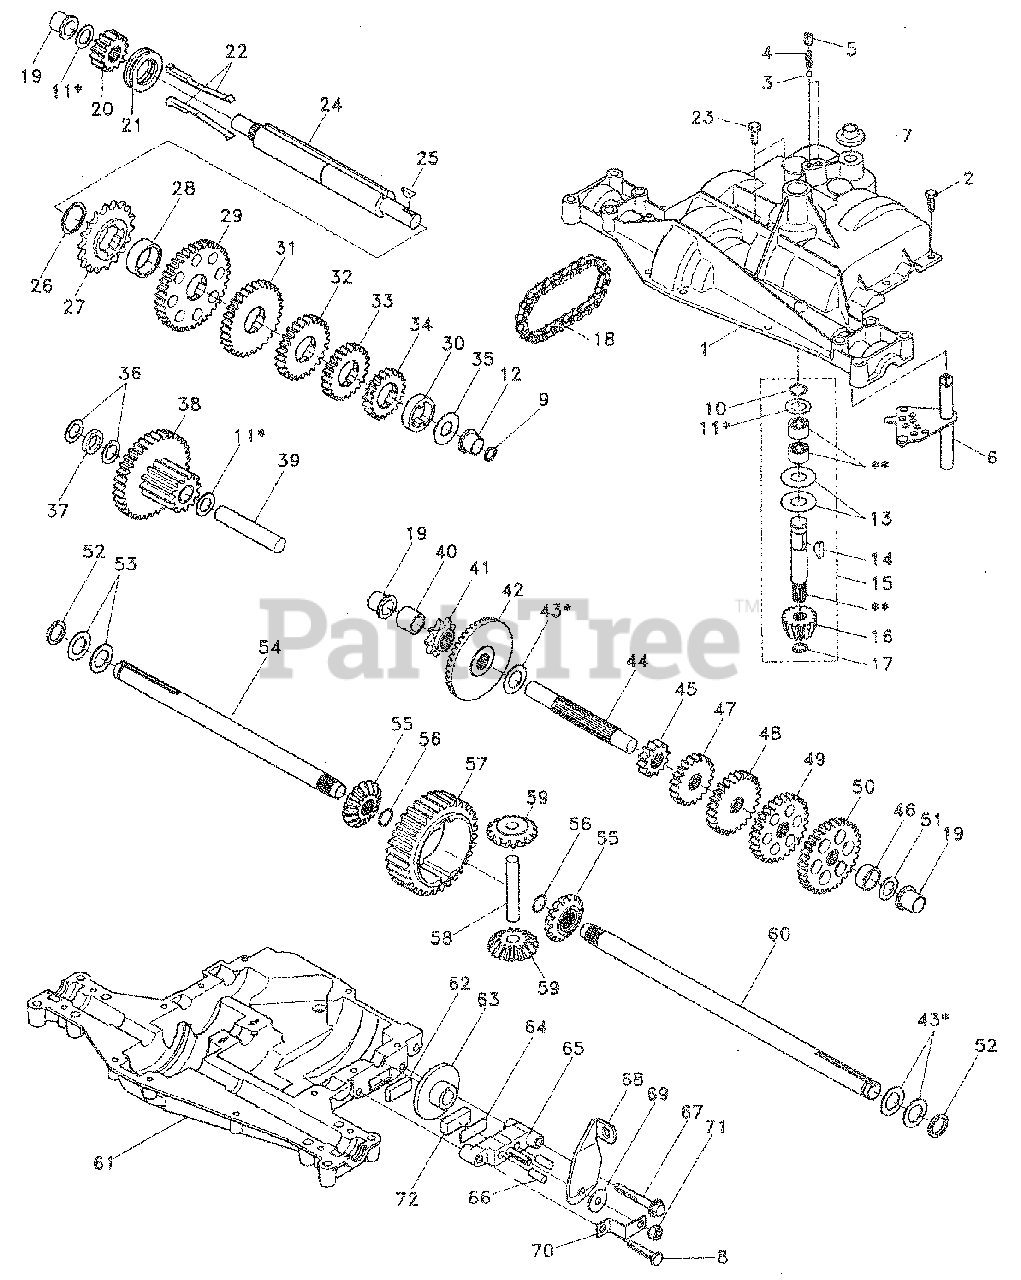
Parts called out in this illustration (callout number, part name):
1	Housing, Upper
2	Screw, Self-Tapping, Large 1/4-20 X.734
3	Ball, Detent
4	Spring, Detent
5	Screw, Set
6	Kit, Shifter Assembly
7	Boot, Shifter
8	Screw, Self-Tapping, Large 5/16-18 x 1.44
9	Square Ring
10	Ring, Retaining
11	Assembly, Kit, Shim .625 Shaft
12	Bearing, Flange
13	Washer, Plain .632 x 1.38 x .046
14	Key, Woodruff, #9
15	Assembly, Kit, Input Shaft
16	Pinion, Bevel, 14 Teeth
17	Ring, Retaining
18	Chain, 24 Pitches
19	Bearing, Flange
20	Gear, Spur, 14 Teeth
21	Collar, Clutch
22	Assembly, Kit, Clutch Keys
23	Screw, Self-Tapping, with Sealer
24	Shaft, intermediate
25	Key, Woodruff, #61
26	Ring, Retaining
27	Sprocket, 18 Teeth
29	Gear, Spur, 37 Teeth
30	Spacer 1.133 x 1.50 x .375
31	Gear, Spur, 30 Teeth
32	Gear, Spur, 25 Teeth
33	Gear, Spur, 22 Teeth
34	Gear, Spur, 19 Teeth
35	Washer, Plain .640 x 1.37 x .061
36	Washer, Plain .632 x 1.00 x .026
37	Spacer .630 x 1.00 x .169
38	Assembly, Gear, Combination of 12 Teeth and 35 Teeth
39	Shaft, idler
40	Spacer .635 x .875 x .755
41	Sprocket, 9 Teeth
42	Gear, Bevel, 42 Teeth
43	Assembly, Kit, Shim .750 Shaft
44	Shaft, Drive
45	Gear, Spur, 12 Teeth
46	Spacer .781 x 1.00 x .375
47	Gear, Spur, 20 Teeth
48	Gear, Spur, 25 Teeth
49	Gear, Spur, 28 Teeth
50	Gear, Spur, 31 Teeth
51	Washer, Plain .632 x 1.00 x .060
52	Washer, Neoprene
53	Washer, Plain .758 x 1.25 x .031
54	Axle, L.H.
55	Gear, Miter, 15 Teeth
56	Ring, Retaining
57	Gear, Spur, 32 Teeth
58	Shaft, Cross
59	Gear, Miter, 15 Teeth
60	Axle, R.H.
61	Housing, Lower
62	Puck, Friction
63	Disc, Brake
65	Jaw, Brake
66	Pin, Dowel
67	Screw, Self-Tapping, Large 5/16-18 x 2.25
68	Lever, Actuating
69	Washer, Plain .321 x 1.00 x .055
70	Bracket, Anti-Rotation
71	Locknut 5/16-24
72	Puck, Friction
73	Grease
